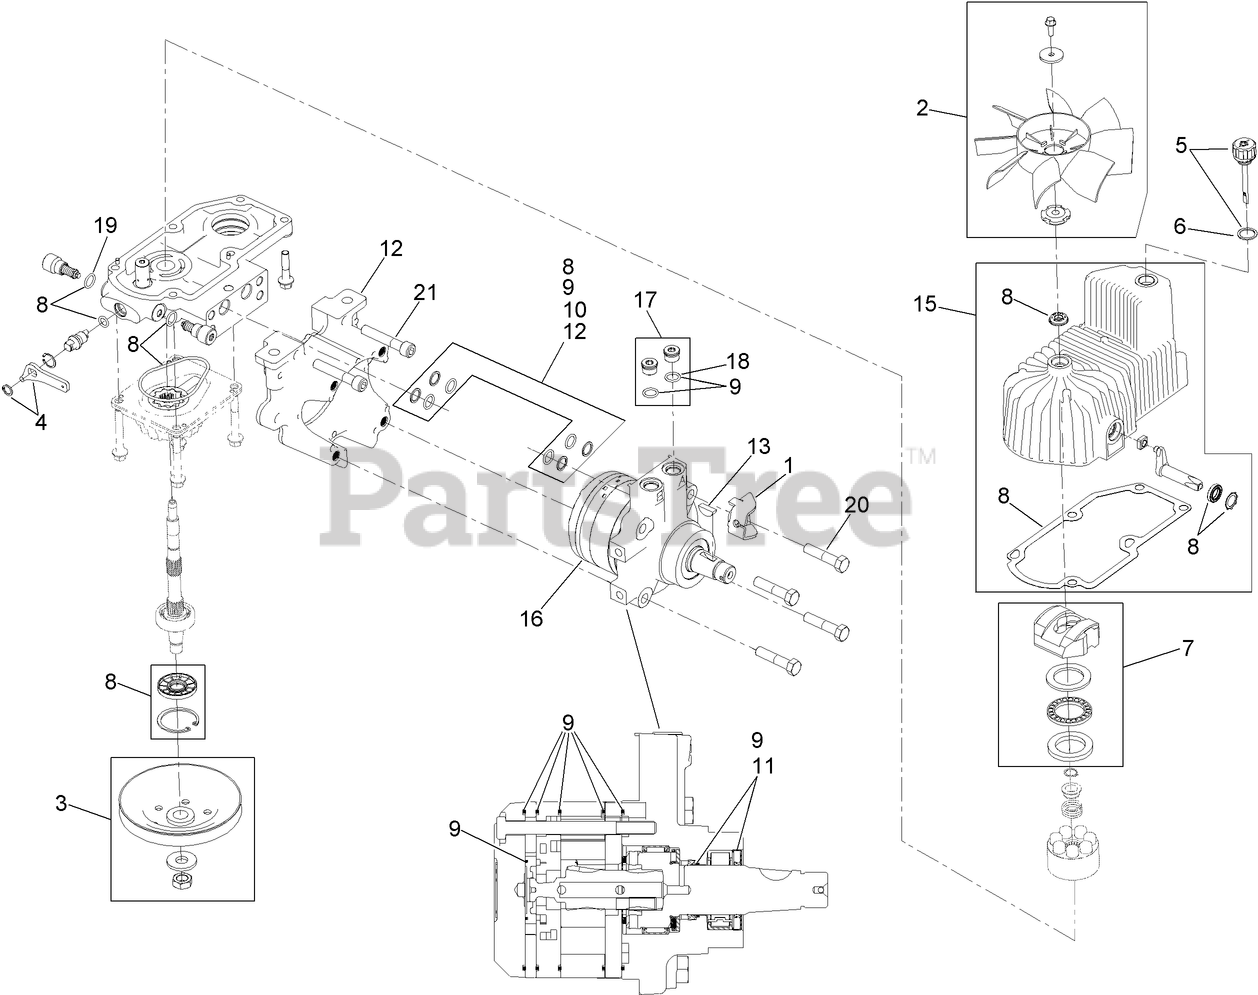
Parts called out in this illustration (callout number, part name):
1	BRACKET-ANCHOR, CABLE
2	FAN KIT
3	PULLEY KIT
4	HANDLE-BYPASS VALVE, HYDRO
5	DIPSTICK-HYDRO W/GASKET
6	GASKET-DIPSTICK, HYDRO
7	SWASH BLOCK KIT
8	PUMP SEAL KIT
9	MOTOR SEAL KIT
10	TUBE SEAL KIT
11	OUTPUT SHAFT SEAL KIT
12	NOSE CUP-UHT
13	KEY-WOODRUFF
15	HOUSING-HYDRO, LH
16	MOTOR-HYDRAULIC LH 240CC
17	MAGNETIC PLUGS SERVICE KIT
18	O-RING
19	O-RING-CHECK VALVE
20	SCREW HH
21	SCREW-HSH
